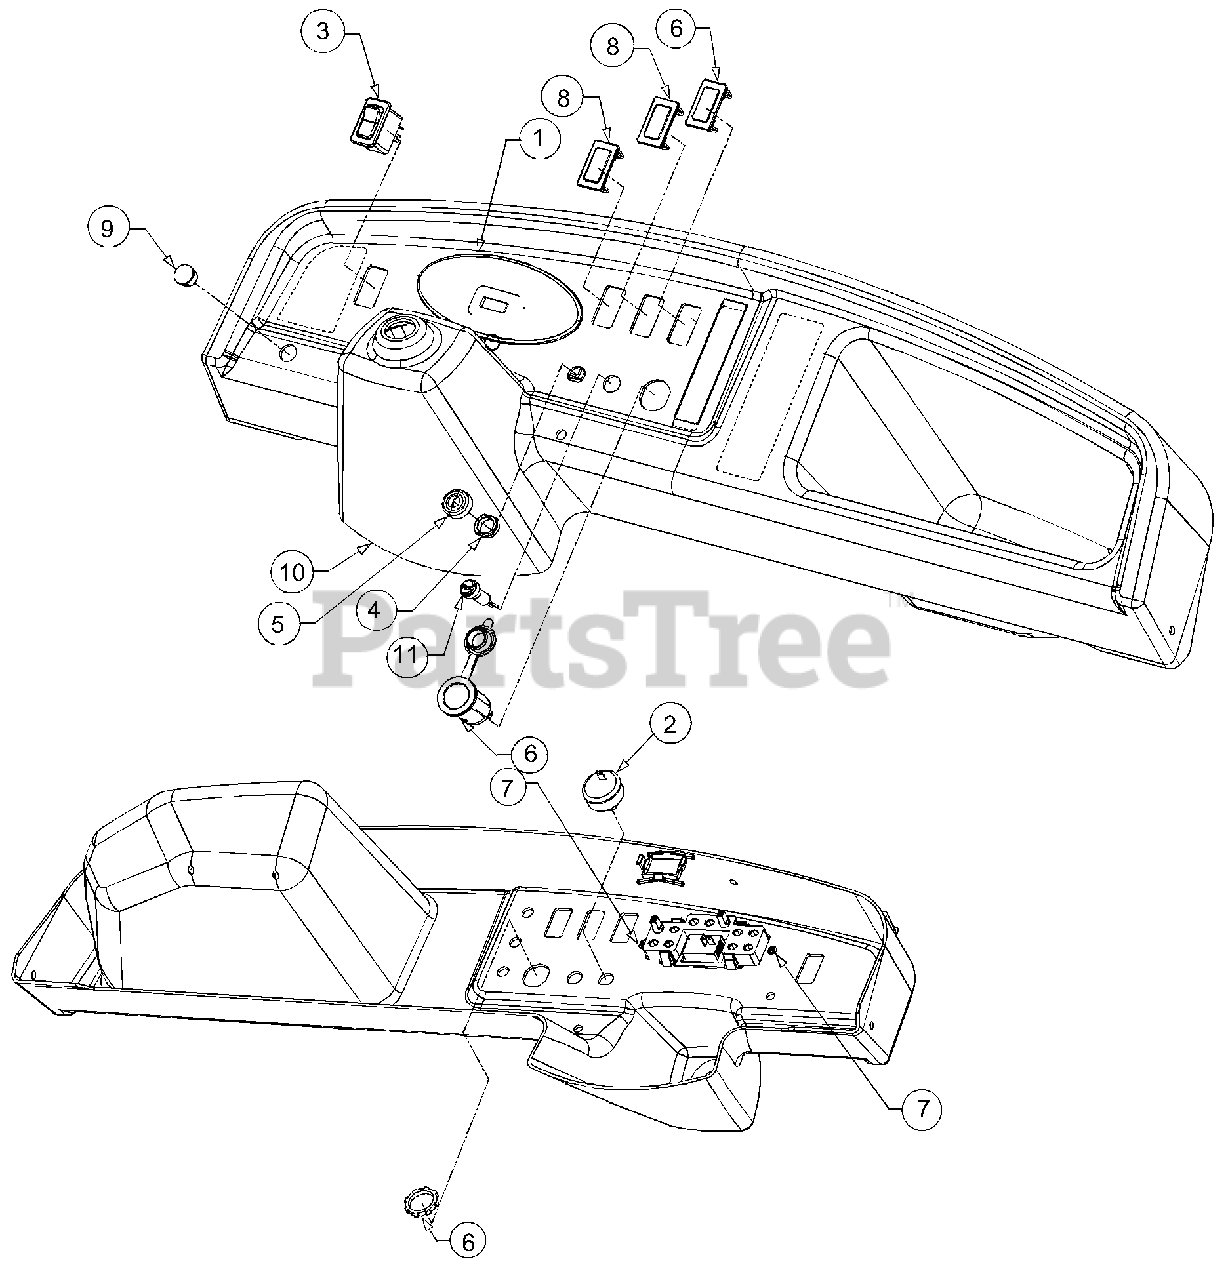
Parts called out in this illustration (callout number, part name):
1	Instrument Panel
2	Switch, Key
3	Rocker Switch, Headlight
4	Ignition Switch Nut, 5/8-32
5	Ignition Switch Cap
6	Receptacle, Power, 12v
7	Nut, Retainer 1/8
10	Dash Panel
11	Switch, Horn
